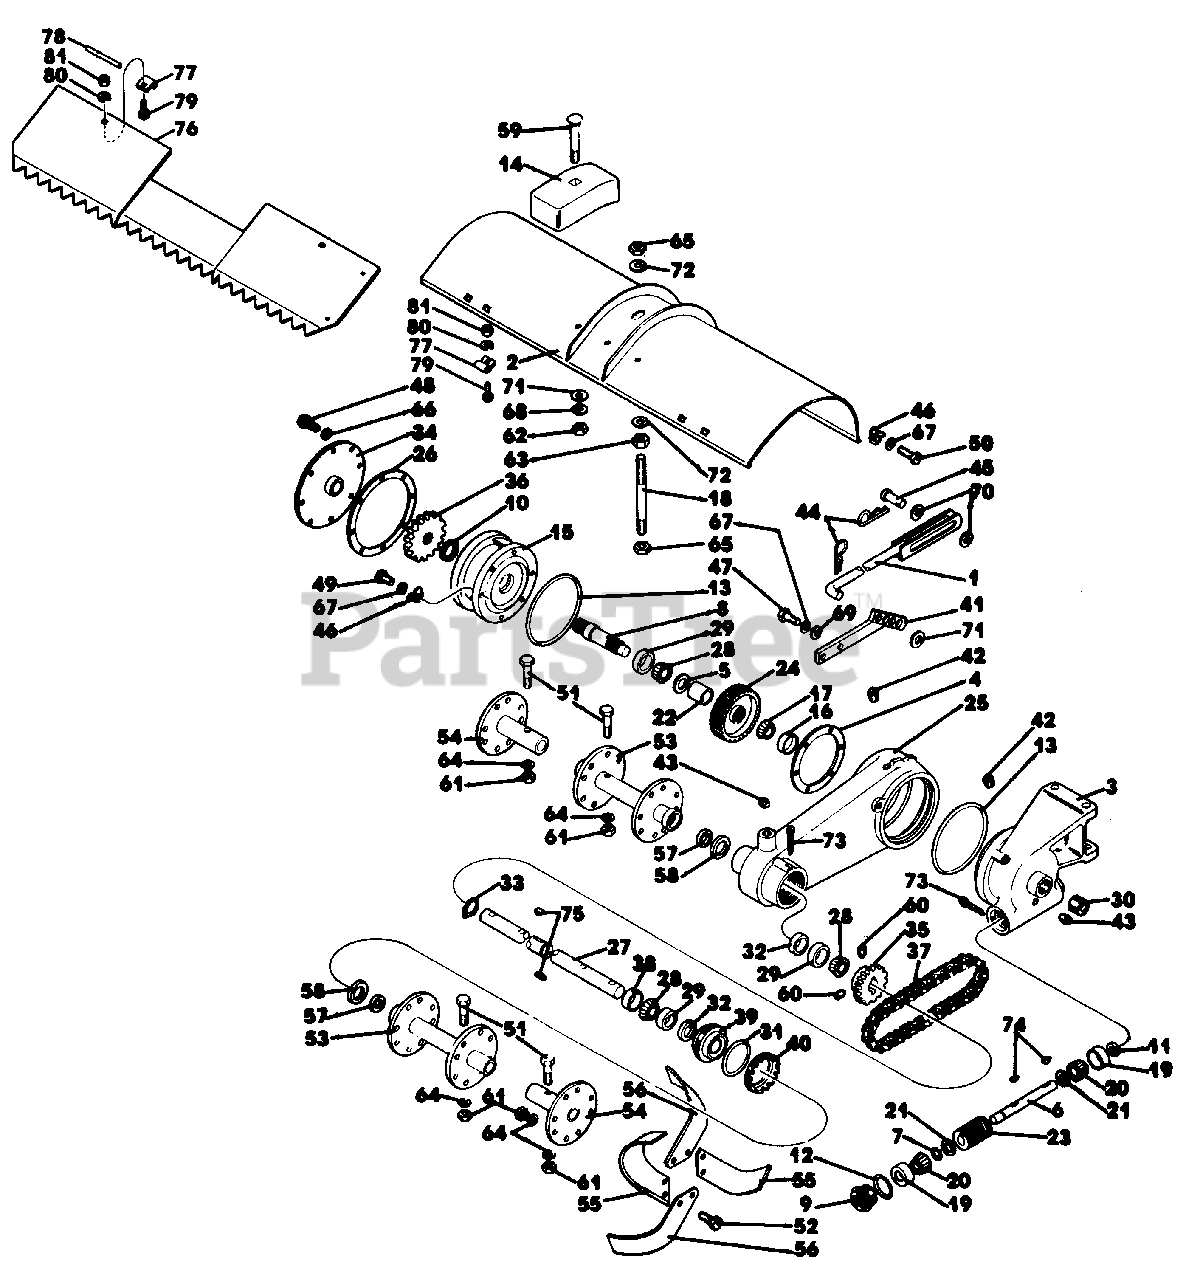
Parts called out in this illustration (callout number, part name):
1	Lift Rod Assembly
2	Tine Shield & Decal Assembly
3	Gear Case
4	Gasket-Gear Case
5	Shim-Bearing Adjustment
6	Worm Shaft
7	Snap Ring
8	Shaft & Sleeve Assembly
9	Plug-Bearing Adjustment
10	Seal
11	Seal
12	O-Ring
13	O-Ring
14	Tiller Weight
15	Bearing Plate
16	Bearing Cup
17	Bearing Cone
18	Tine Shield Stud
19	Bearing Cup
20	Bearing Cone
21	Worm Spacer
22	Worms Wheel Spacer
23	Worm
24	Worm Wheel
25	Chain Case
26	Gasket-Cover
27	Tine Shaft
28	Bearing Cone
29	Bearing Cup
30	Pipe Plug-Socket
31	O-Ring
32	Oil Seal
33	Snap Ring
34	Chain Case Cover Assembly
35	Sprocket-15T
36	Sprocket-19T
37	Chain, #60, includes #18381 Connector Link
38	Spacer
39	Plug-Bearing Adjustment
40	Lock Ring
41	Lift Arm Assembly
42	Vent Plug Assembly
43	Pipe Plug
44	Spring Clip
45	Clevis Pin
46	Lug Washer
47	Cap Screw, Hex 3/8-16 x 1" Plated, Grade 5
48	Cap Screw, Hex Hd. 1/4-20 x 1/2 Plated, Grade 5
49	Cap Screw, Hex Hd. 3/8-16 x 7/8 Plated, Grade 5
50	Cap Screw, Hex Hd. 3/8-16 x 1-1/4 Plated, Grade 5
51	Cap Screw, Hex 7/16-20 x 2-1/4 Plated, Grade 5
52	Tine Bolt
53	Inner Tine Hub Assembly
54	Outer Tine Hube Assembly
55	Tine-R.H.
56	Tine-L.H.
57	Inner Felt Seal
58	Intermediate Felt Seal
59	Bolt Carriage 1/2-13 x 5" Plated
60	Setscrew, Hex Socket Hd. Cup Pt. 5/16-18 X 5/16
61	Nut, Hex 7/16-20 Plated
62	Nut, Hex 1/2-13 Plated
63	Nut, Hex Jam 5/8-11
64	Washer, Spring Lock 7/16 Plated
65	Nut, Hex Self Locking 5/8-11
66	Washer, Spring Lock 1/4 Plated
67	Washer, Spring Lock 3/8 Plated
68	Washer, Spring Lock 1/2 Plated
69	Washer, Flat SAE 3/8 Plated
70	Washer, Flat 7/16 Plated
71	Washer, Flat 1/2 Plated
72	Washer, Flat 5/8 Plated
73	Pin, Cotter 1/8 x 3/4 Plated
74	Key, Woodruff 3/16 x 5/8
75	Key, Hypro 1/4 x 7/8 Heat Treated
76	Guard Assembly
77	Hinge
78	Hinge Pin
79	Bolt, Carriage 5/16-18 x 3/4 Plated.
80	Washer, Spring Lock 5/16 Plated
81	Nut, Hex 5/16-18 Plated
